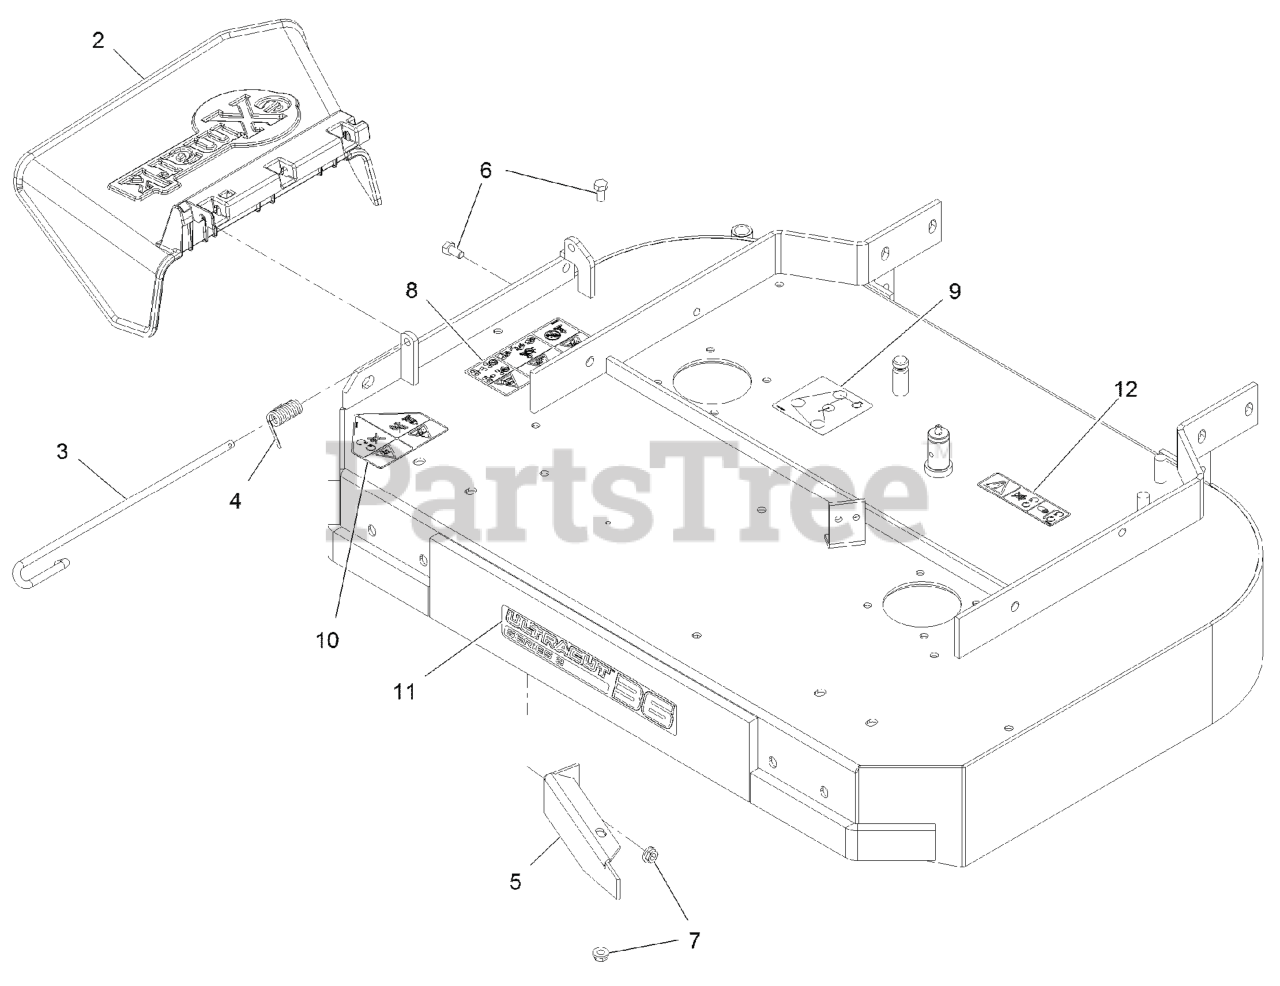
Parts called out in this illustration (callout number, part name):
2	CHUTE DEFLECTOR XRK M056
3	PIN-CHUTE
4	SPRING, TORSION
5	BAFFLE-DOGLEG
6	SCREW-HH
8	DECAL-WARNING THROWN OBJ
9	DECAL-BELT ROUTING 32-36
10	DECAL-DANGER
11	Decal-Ultracut 36 Series 2
12	DECAL-COVER, MISSING
